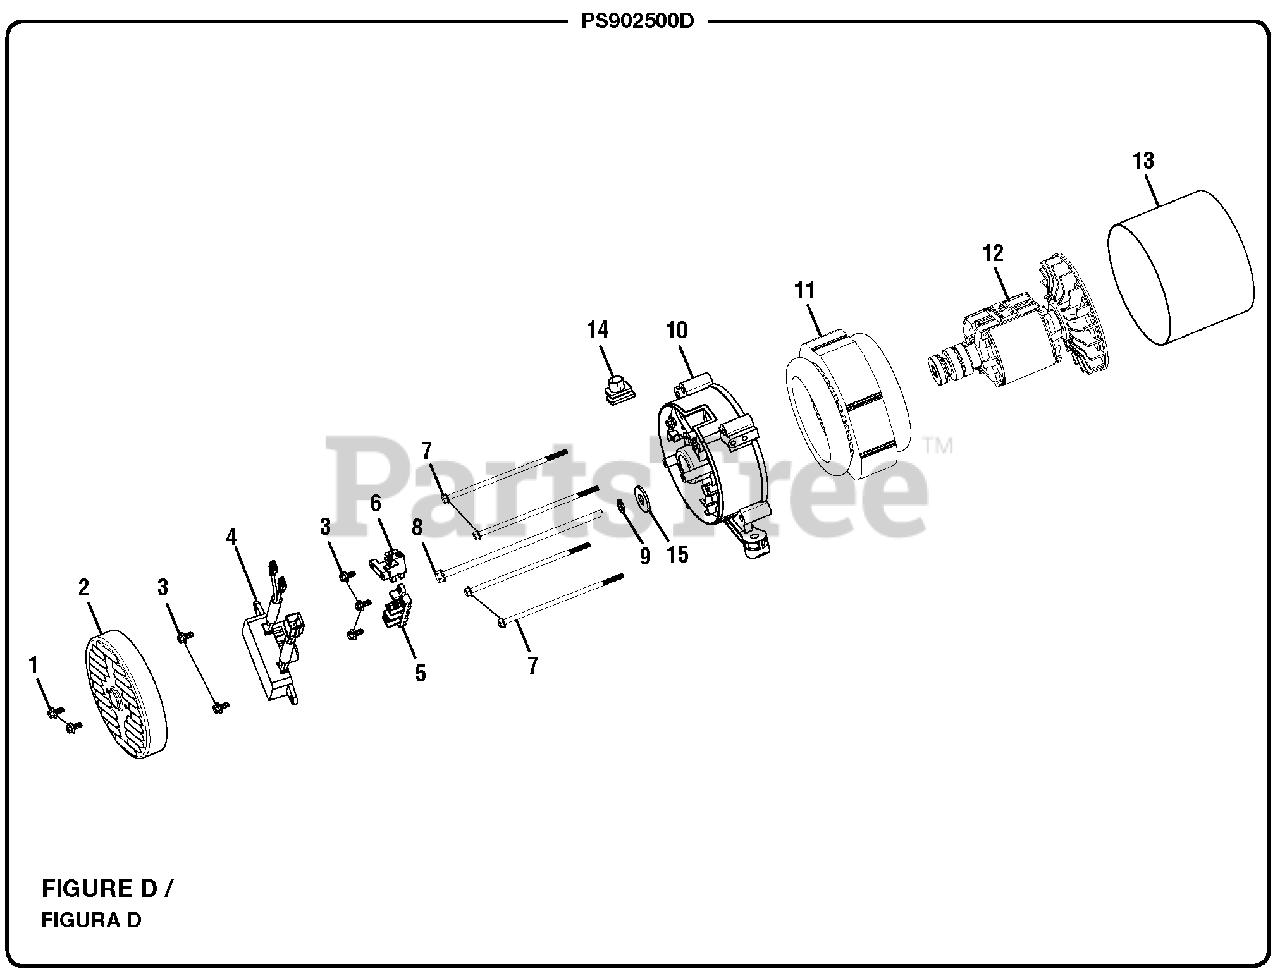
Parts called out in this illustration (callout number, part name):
1	Bolt (M5 x 12 mm, Flange Hd.)
2	Brush Cover
3	Bolt (M5 x 16 mm, Flange Hd.)
4	Automatic Voltage Regulator
5	Terminal Block
6	Brush Assembly
7	Stator Bolt (M6 x 150 mm)
8	Rotor Bolt (M8 x 198 mm)
9	Spring Washer (M8)
10	Bearing Support
14	Rubber Boot
15	Washer (M8)
